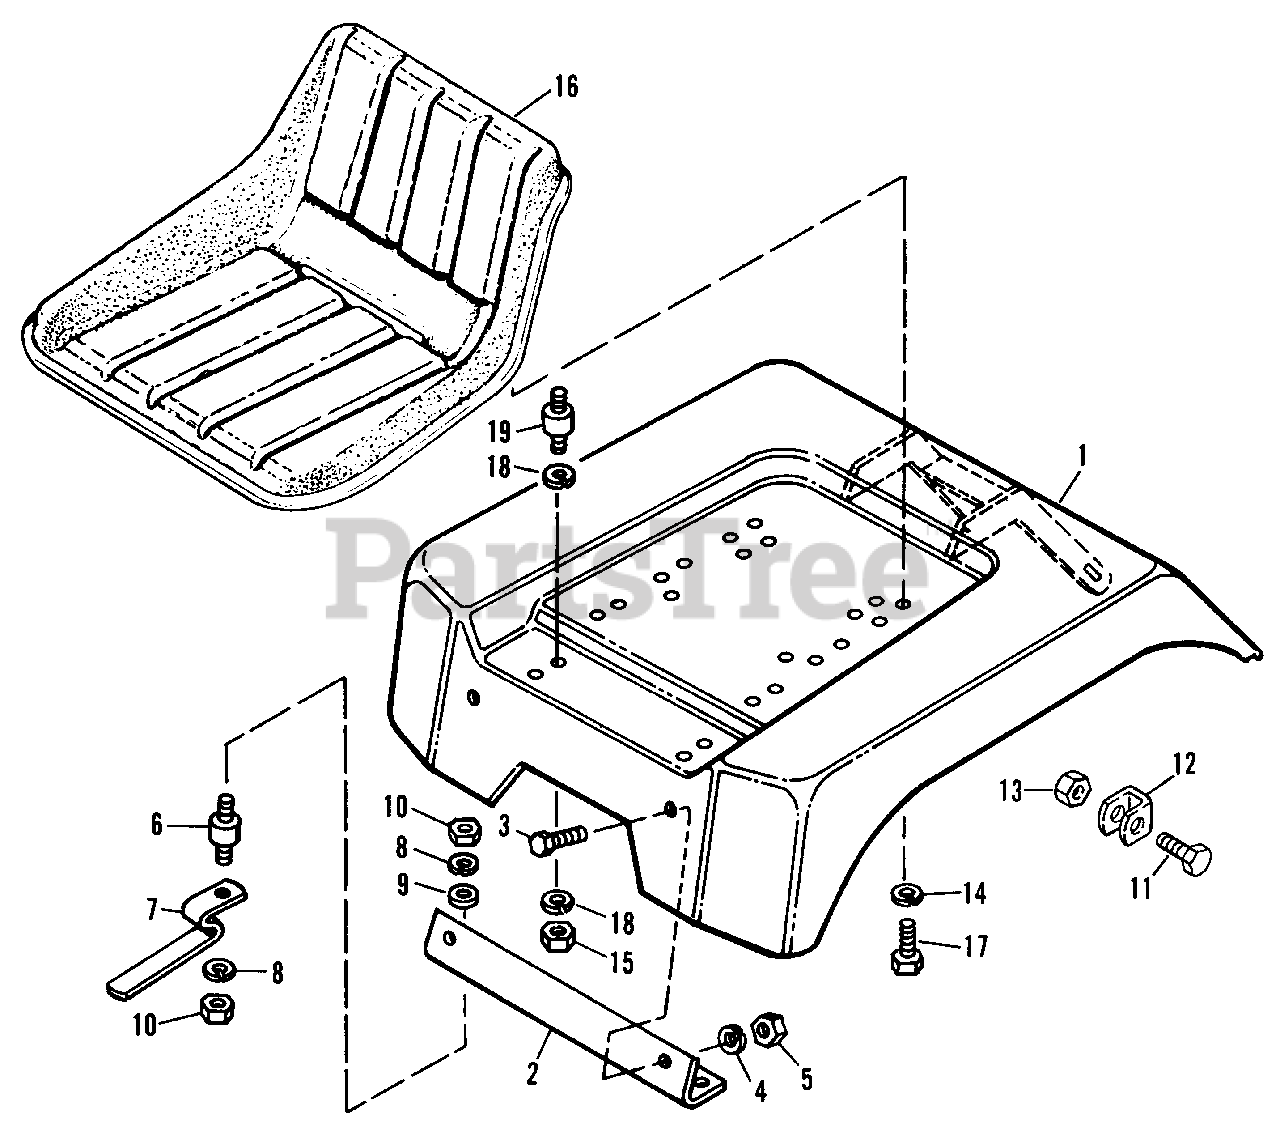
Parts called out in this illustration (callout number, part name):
1	Seat Deck Assembly
2	Seat Deck Bracket, Front
3	Hex Capscrew, 5/16"-18 x 5/8"
4	Lockwasher, 5/16"
5	Full Hex Nut, 5/16"-18
6	Cushion Connector, Front
7	Spring Clip
8	Lockwasher, 5/16"
9	Washer, 1/4"
10	Full Hex Nut, 5/16"-18
11	Hex Capscrew, 3/8"-16 x 1-1/4"
12	Seat Deck Stop
13	Full Hex Lock Nut, 3/8"-16
14	Lockwasher, 5/16"
15	Full Hex Nut, 5/16"-18
16	Contour Seat Assembly
17	Hex Capscrew, 5/16"-18 x 5/8"
18	Lockwasher, 5/16"
19	Cushinon Connector
